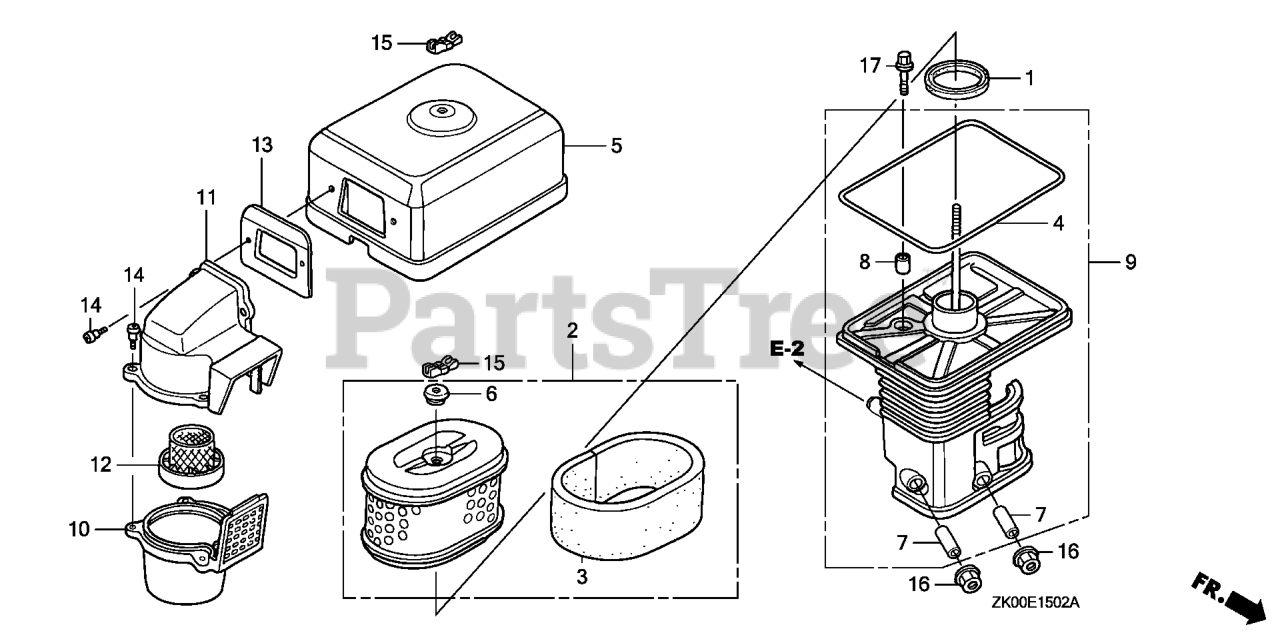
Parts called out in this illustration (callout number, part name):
1	GASKET, ELBOW
2	ELEMENT, AIR CLEANER (DUAL) Use up to Engine SN 2115700.
2	ELEMENT, AIR CLEANER (DUAL)
3	FILTER (OUTER)
4	GASKET, AIR CLEANER COVER
5	COVER, AIR CLEANER (DUAL)
6	GROMMET, AIR CLEANER
7	COLLAR, AIR CLEANER Use from Engine SN 1786085.
8	COLLAR B, AIR CLEANER
9	ELBOW, AIR CLEANER
10	CASE, PRE AIR CLEANER
11	CAP, PRE AIR CLEANER
12	GUIDE, PRE AIR CLEANER
13	PLATE, PRE AIR CLEANER
14	BOLT, MUDGUARD
15	WINGNUT, TOOL BOX SETTING
16	NUT, FLANGE (6MM)
17	BOLT, FLANGE (6X20)
